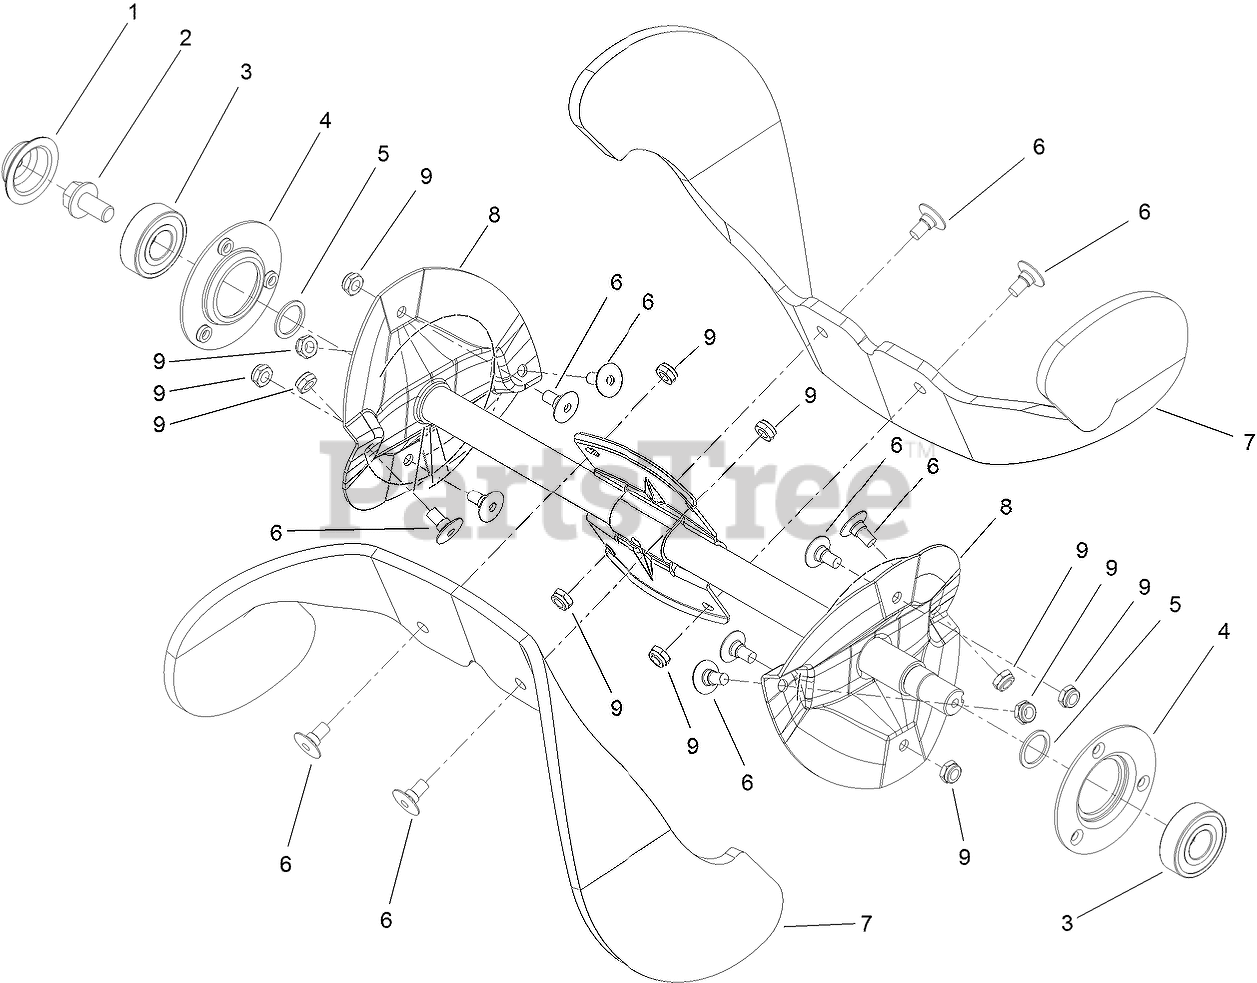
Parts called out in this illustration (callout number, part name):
1	CAP-SIDEPLATE, RH
2	SCREW-HWH
3	BEARING-BALL
4	FLANGE-BEARING
5	WASHER-THRUST
6	SCREW
7	BLADE-ROTOR
8	ROTOR ASM
9	NUT-LOCK, NI
